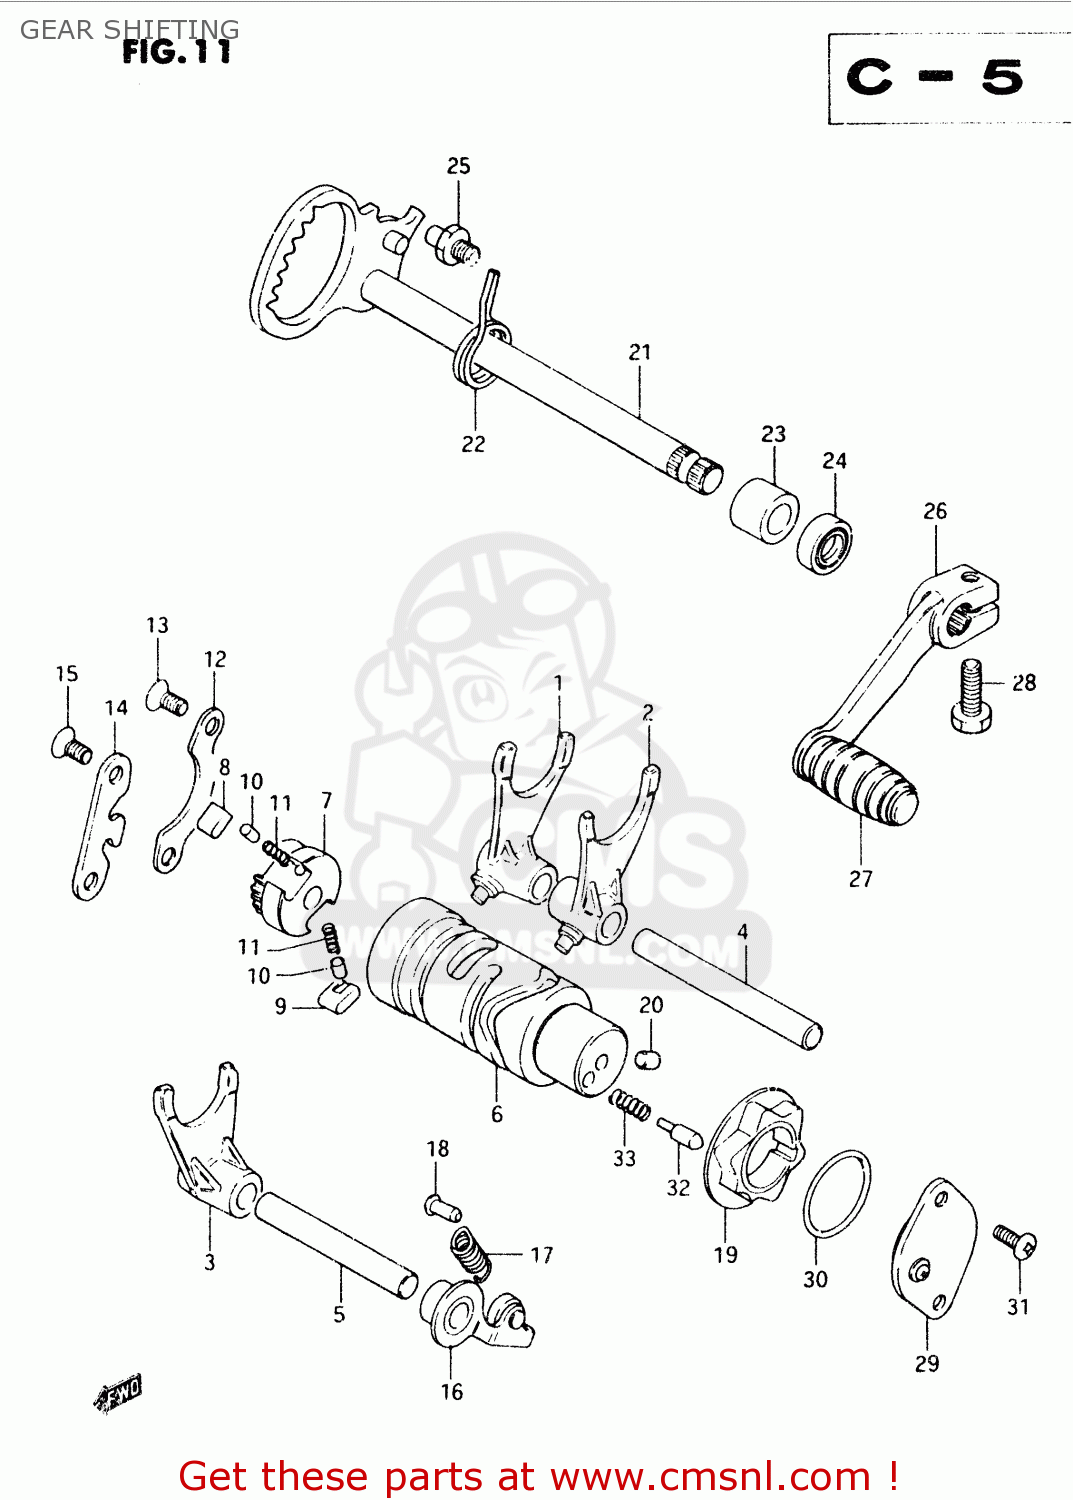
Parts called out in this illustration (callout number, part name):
1	FORK,GEAR SHIFT NO.1
2	FORK, GEAR SHIFT N-2
3	FORK,GEAR SHIFT NO.2
4	SHAFT,GEAR SHIFT FORK
5	SHAFT,GEAR SHIFT FORK
6	CAM,GEAR SHIFT
7	GEAR,GEARSHIFT CAM DRIVE
8	PAWL,GEAR SHIFT NO.1
9	PAWL,GEAR SHIFT NO.2
10	PIN(5X8)
11	SPRING
12	LIFTER,GEAR SHIFT POLE
13	SCREW
14	GUIDE,GEAR SHIFT CAM
15	SCREW
16	STOPPER,GEAR SHIFTING CAM
17	SPRING
18	RIVET
19	PLATE,GEAR SHIFT CAM STOPPER
20	PIN 4X6
21	SHAFT,GEAR SHIFT
22	SPRING
23	SPACER(12X20X15.3)
24	OIL SEAL
25	STOPPER,GEAR SHIFT CAM
26	LEVER ASSY,GEAR SHIFT
27	RUBBER,GEAR SHIFT PEDAL
28	BOLT
29	BODY,GEAR SHIFT SWITCH
30	O-RING (D:2.4 ID:26.2)
31	SCREW
32	PIN(5X15.5)
33	SPRING
